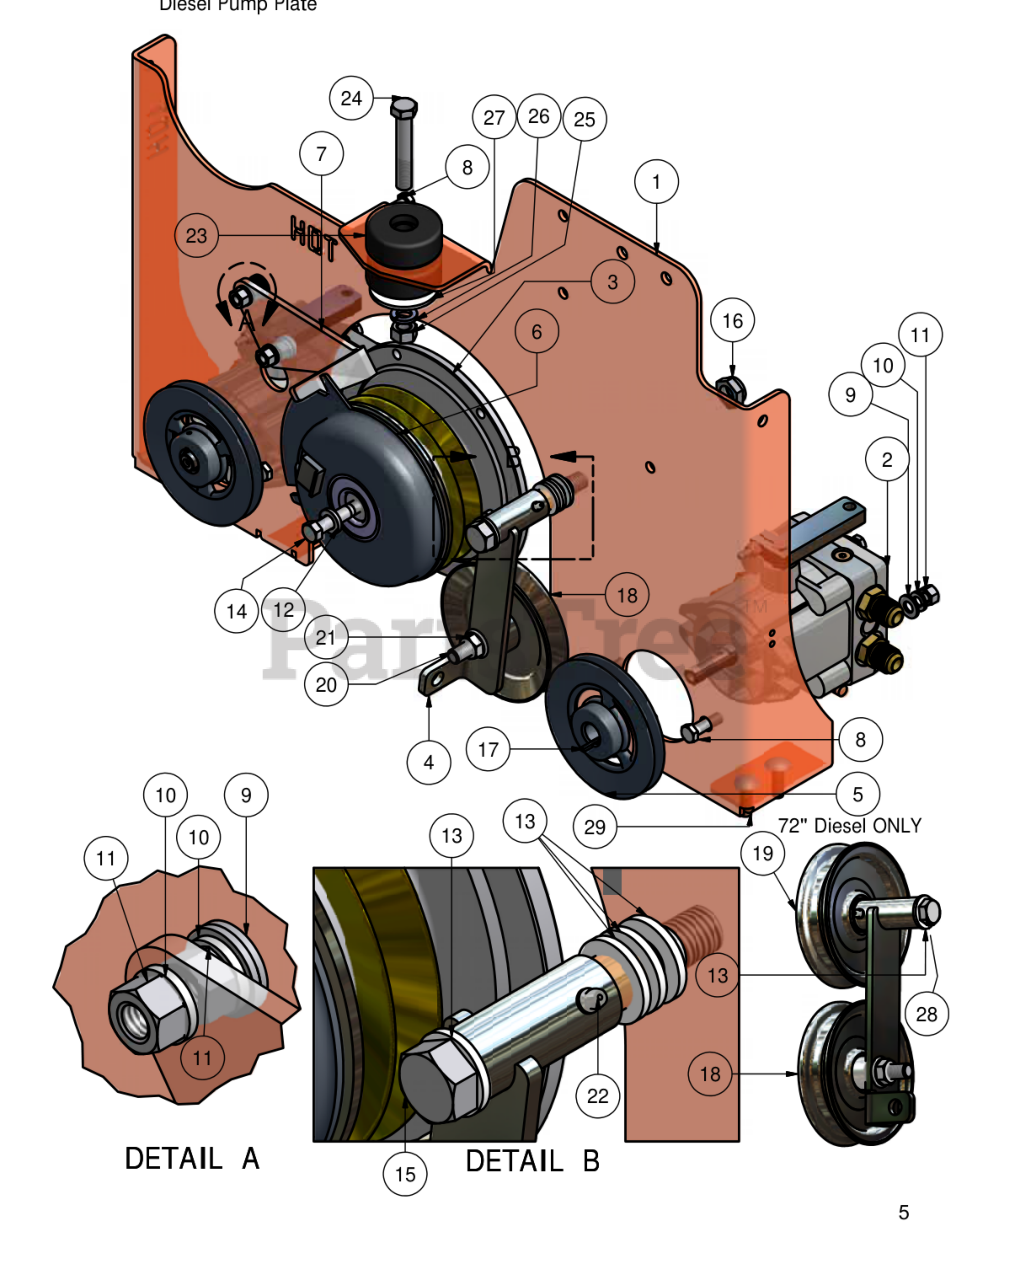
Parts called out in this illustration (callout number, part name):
1	Diesel Pump Plate
2	Left Hydraulic Pump
2	Right Hydraulic Pump
3	Stub Shaft
4	Pump Idler Bracket
5	5" Pump Pulley
6	Diesel Clutch
7	PTO Engager Holder
8	3/8" x 1 1/2" Hex Bolt
9	3/8" Flat Washer
10	3/8" Lock Washer
11	3/8" Hex Nut
12	7/16" Lock Washer
13	.635 ID Plastic Washer
14	7/16" x 2 3/4" Fine Thread Bolt
15	5/8" x 4 1/2" Hex Bolt (60")
16	5/8" Nylock (1/2 Jam)
17	5mm x 1.25" Key
18	4 3/4" Idler Pulley
19	Diesel Idler Pulley
20	1/2" x 2 1/2" Bolt
21	1/2" Nylock Flange Nut
22	Grease Fitting
23	Rubber Isolator
24	1/2" x 3" Hex Bolt
25	1/2" Hex Nut
26	1/2" Lock Washer
27	Vibration Mount Snubbing Washer
28	5/8" x 5 1/2" Hex Bolt (72")
29	3/8" x 1 1/4" Carriage Bolt
